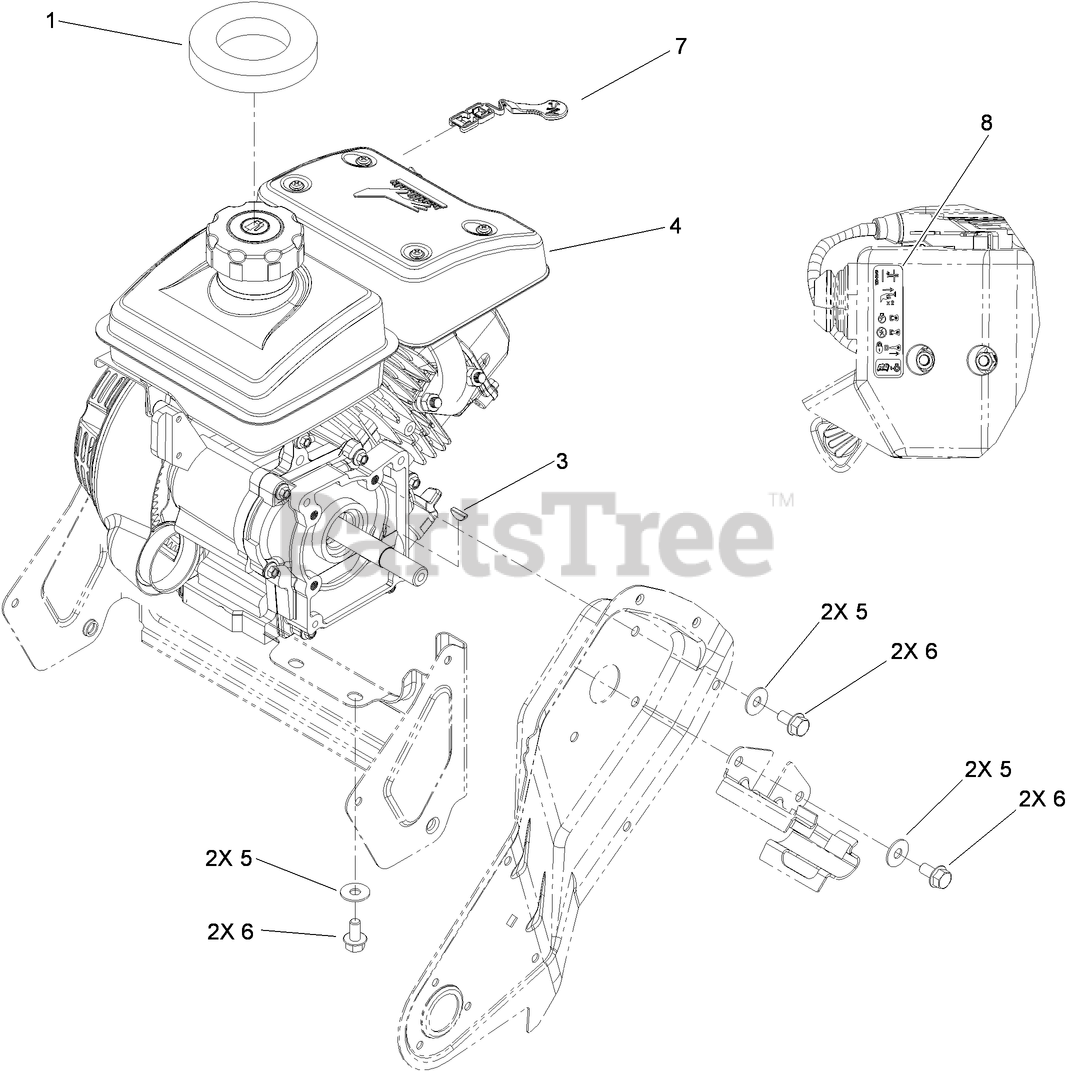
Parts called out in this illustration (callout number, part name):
1	SEAL-TANK
3	KEY-WOODRUFF
4	ENGINE-154FS-1
5	WASHER-BELLEVILLE
6	SCREW-HHF
7	LEVER-CHOKE
8	DECAL-CONTROLS, ENGINE
